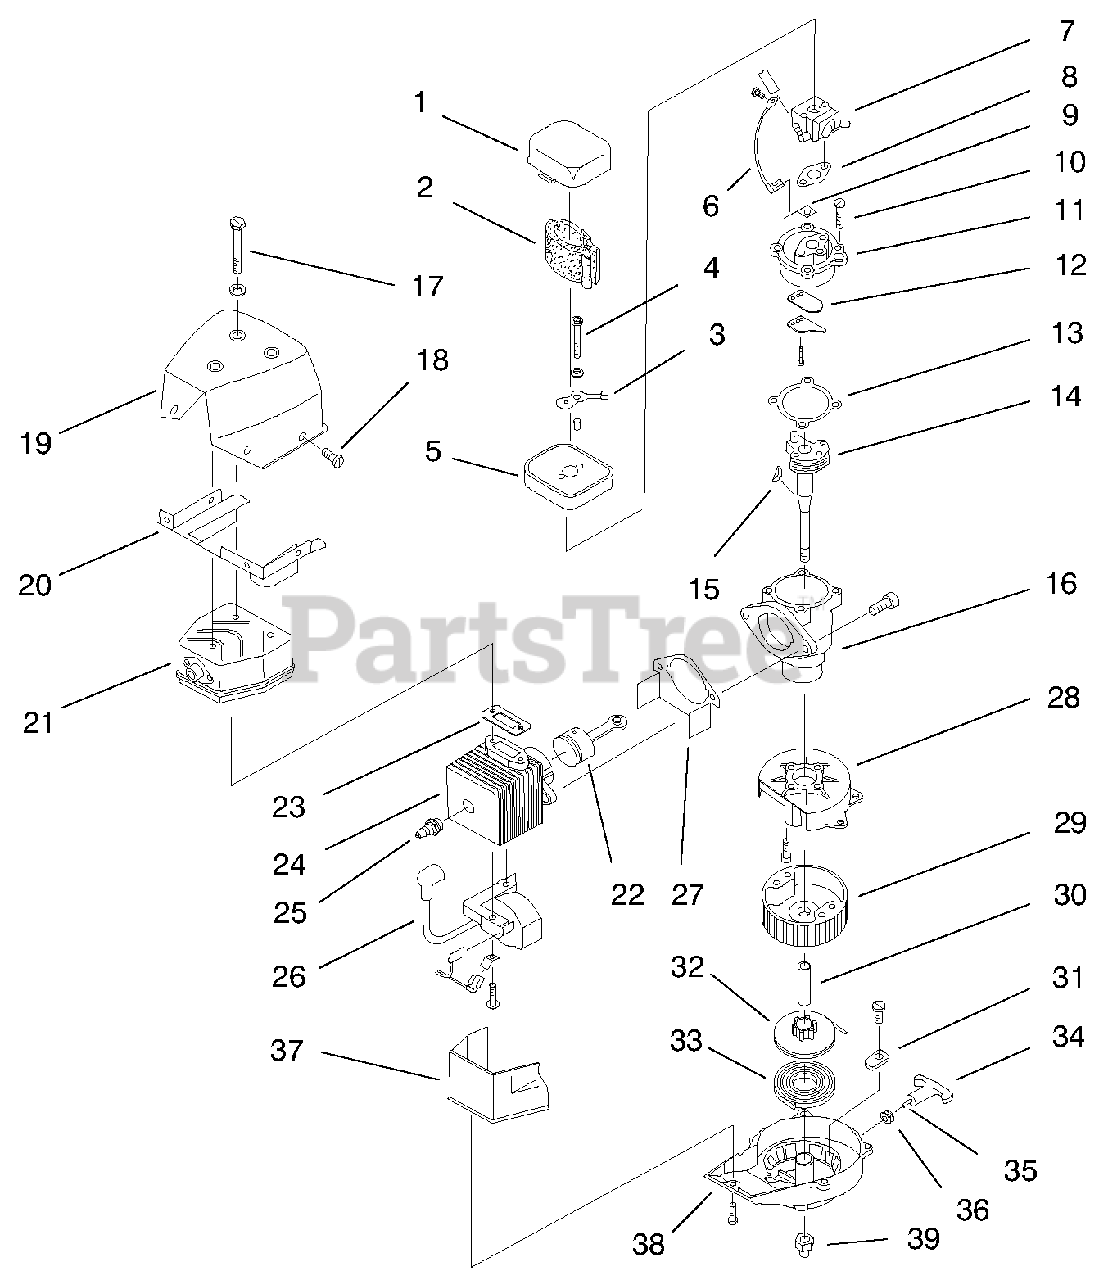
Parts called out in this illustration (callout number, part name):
1	Air Cleaner Cover Asm.
2	Air Cleaner Filter
3	Choke Lever Asm.
4	Mounting Bolt Asm.
5	Air Cleaner Base
6	Wire Lead
7	Carburetor
8	Carburetor Gasket
9	Ground Tab
10	Reed Plate Mounting Screw
11	Complete Reed Plate Asm.
12	Reed Asm.
13	Reed Plate Gasket
14	Crank Shaft Asm.
15	Flywheel Key
16	Crankcase Service Asm. (Incl. Ref. #10, 13-16)
17	Muffler Mounting Bolt
18	Mounting Screw Asm.
19	Upper Heat Shield
20	Lower Heat Shield
21	Muffler Asm.
22	Piston and Rod Asm.
23	Exhaust Gasket
24	Cylinder Asm.
25	Spark Plug
26	Module Asm.
27	Cylinder Gasket
28	Shroud Asm.
29	Flywheel Asm.
31	Pulley Retainer Asm.
32	Recoil Pulley Asm.
33	Recoil Spring
34	Pull Handle
36	Rope Guide
37	Shroud Extension
38	Starter Housing Asm.
39	Crankshaft Extension
